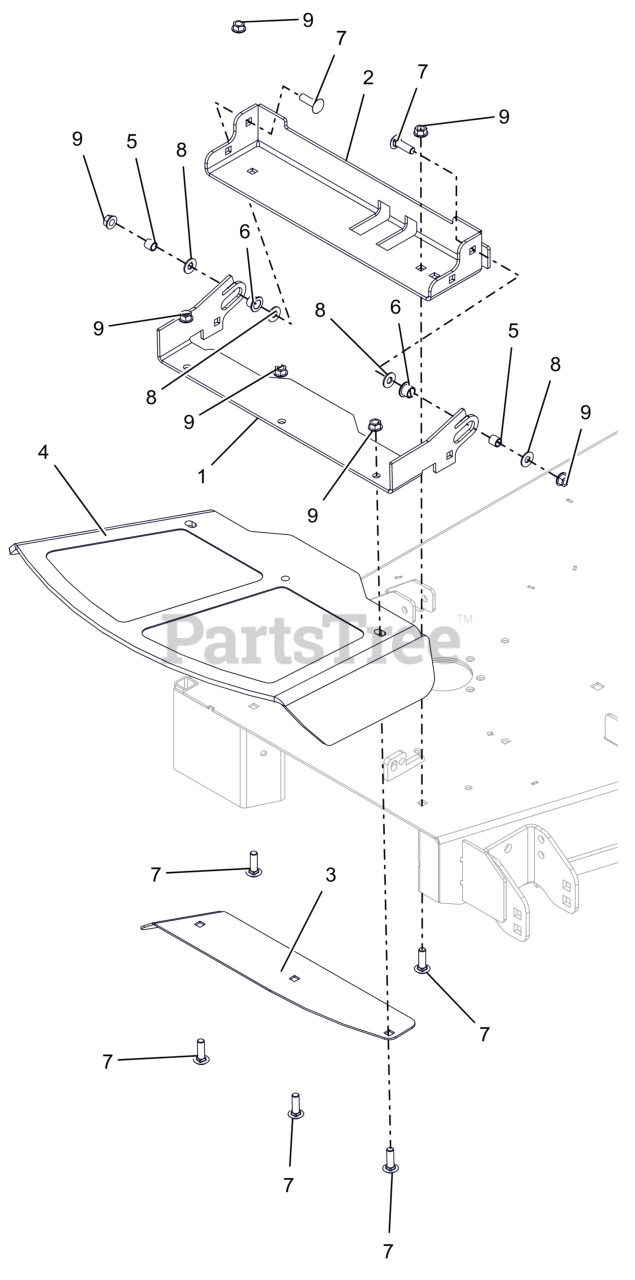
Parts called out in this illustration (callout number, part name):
1	BRKT, CHUTE MOUNT (ORANGE)
2	BASE, DISCHARGE CHUTE MTG BRKT (ORANGE)
3	48-60 DISCH CHUTE CLMP PLT-ORG
4	CHUTE, FORMED RUBBER DISCHARGE
5	SPCR, .385X.500X.350
6	BSHG, FLANGED .50X.625X.50X.062
7	BLT,RHSSN .38-16X1.25 G5 ZCC
8	WSHR, HDND .375X.875X.064 ZCC
9	NUT-LK-CTR-FLG .375-16 GF ZCC
